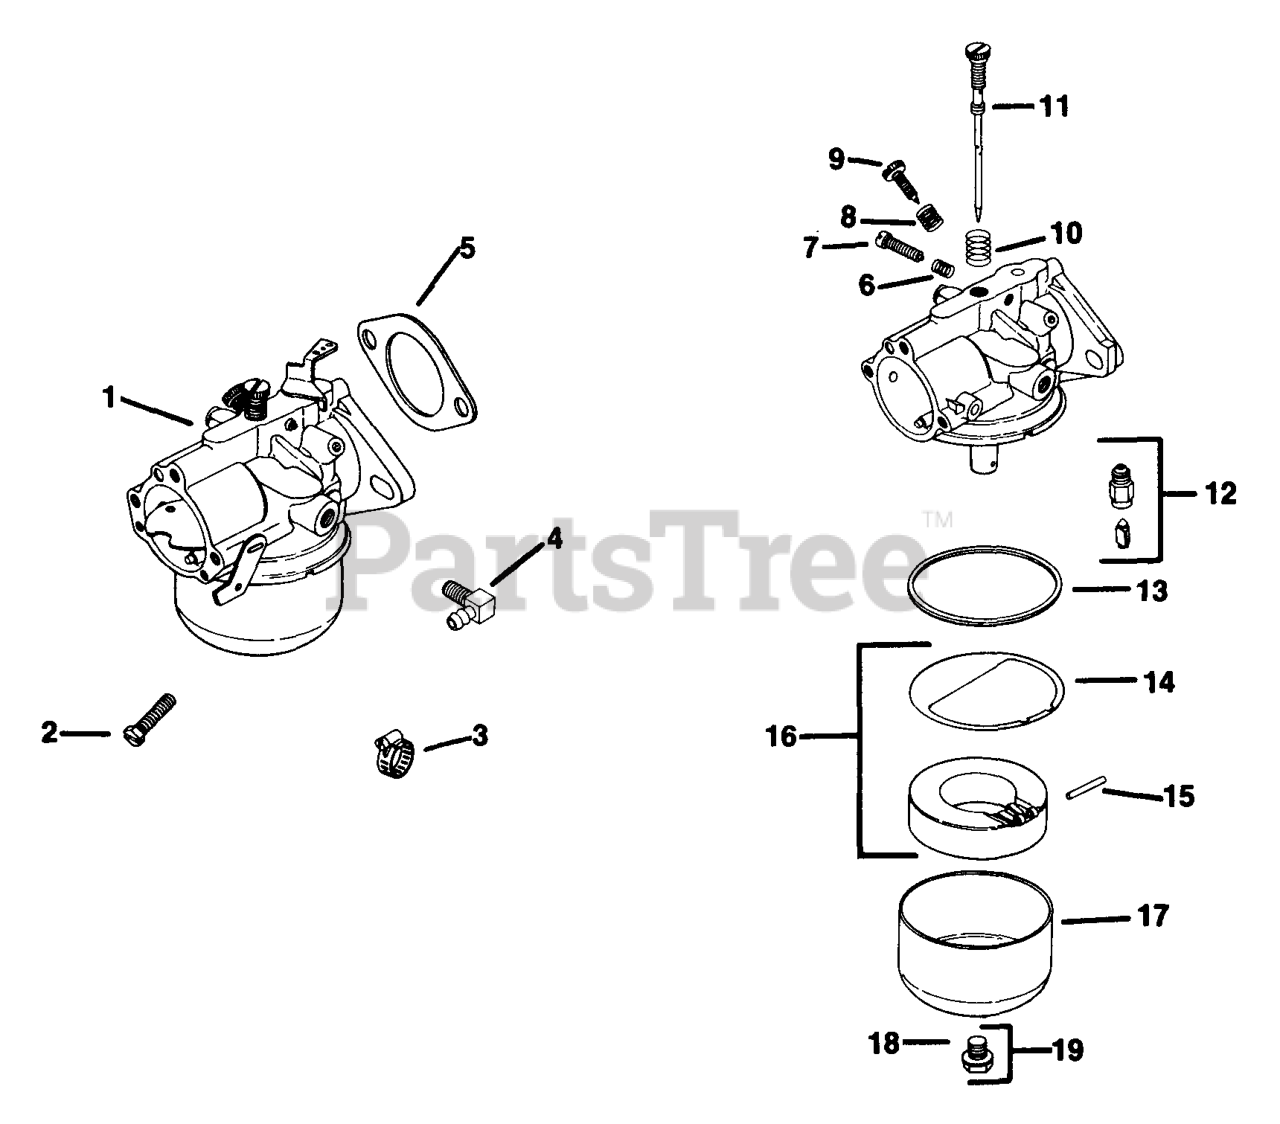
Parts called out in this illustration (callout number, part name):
1	CARBURETOR - USE 41 853 07
2	SCREW-DISCONTINUED
3	CLAMP, HOSE 1/2" USE 25 237 14-S
4	CONNECTOR, 90 DEG. HOSE
7	SCREW, SPECIAL
8	SPRING-(#DSC)
9	SCREW - DISCONTINUED
11	NEEDLE - DISCONTINUED
12	Needle and seat
16	KIT, FLOAT REPAIR - DISCONTINUED
19	NUT - DISCONTINUED
2575701-S	KIT, CARBURETOR REPAIR
